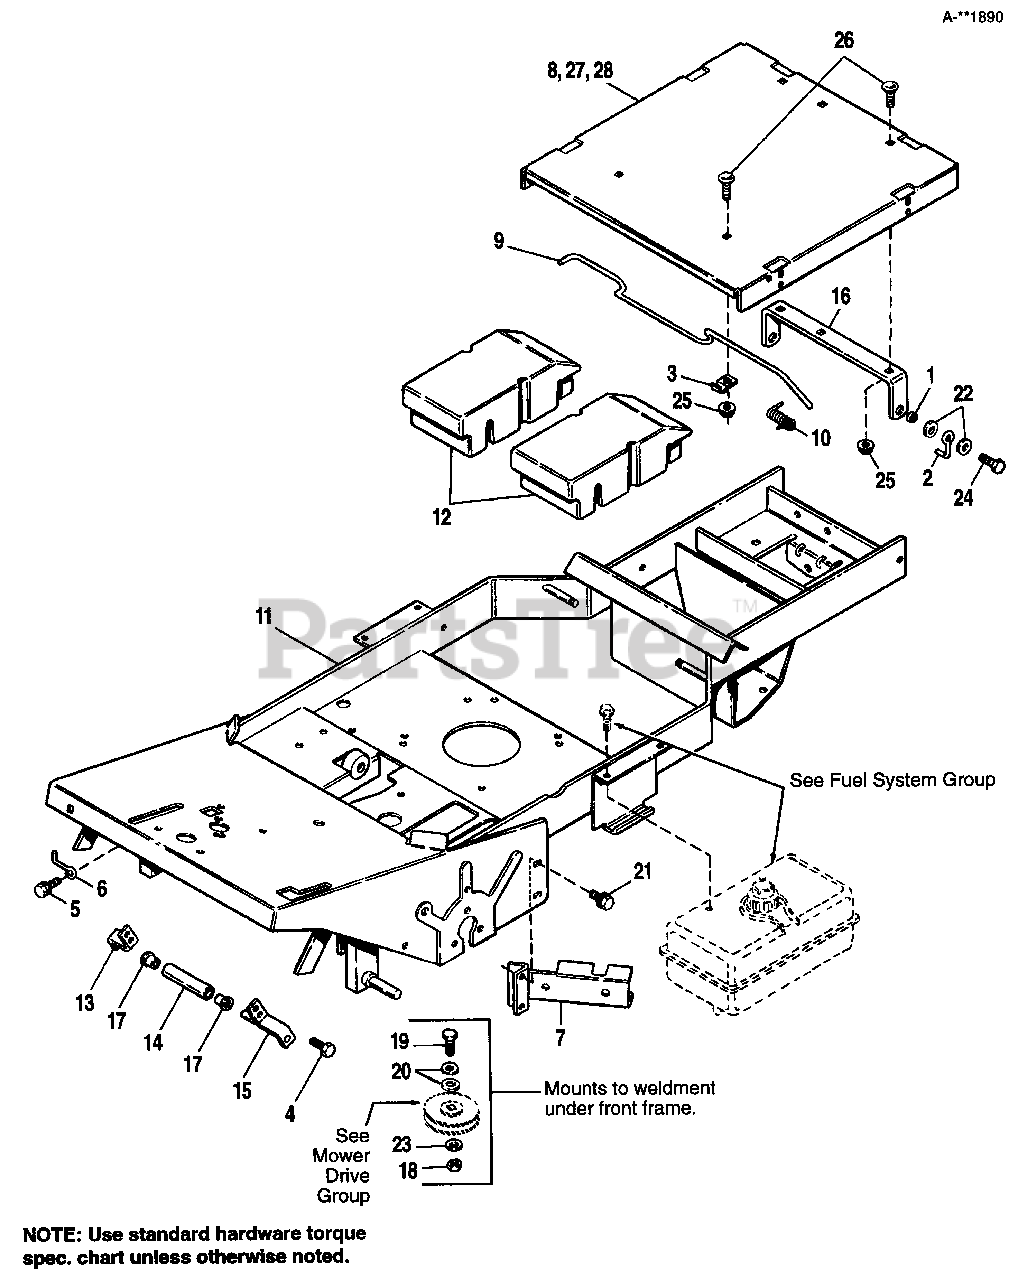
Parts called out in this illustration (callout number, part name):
2	STOP, Pivot
4	SCREW, Taptite, 5/16-18 x 3/4
5	SCREW, Taptite, 5/16 x 3/4
6	RETAINER, Cable
7	SUPPORT ASSY., Gas Tank
8	PLATFORM, Orange
10	SPRING, Torsion
11	FRAME ASSY.
12	WEIGHT, Rear
13	BRACKET, Roller, Front
14	TUBE, Pivot
15	BRACKET ASSY.
16	BRACKET, Pivot
17	BUSHING, Flanged
18	NUT, Hex, Flange Lock, 3/8-16
19	CAPSCREW, Hex Hd., 3/8-16 x 1-1/2
20	WASHER, Plain, 3/8
21	SCREW, Taptite, 5/16-18 x 1/2
22	WASHER, Plain
23	WASHER, Plain
24	SCREW, Taptite, 5/16-18 x 1-1/4
25	NUT, Hex, Whizlock, 5/16-18
26	CARRIAGE BOLT, 5/16-18 x 3/4
27	PLATFORM, Red (Massey Ferguson)
28	PLATFORM, Green (Deutz-Allis models)
